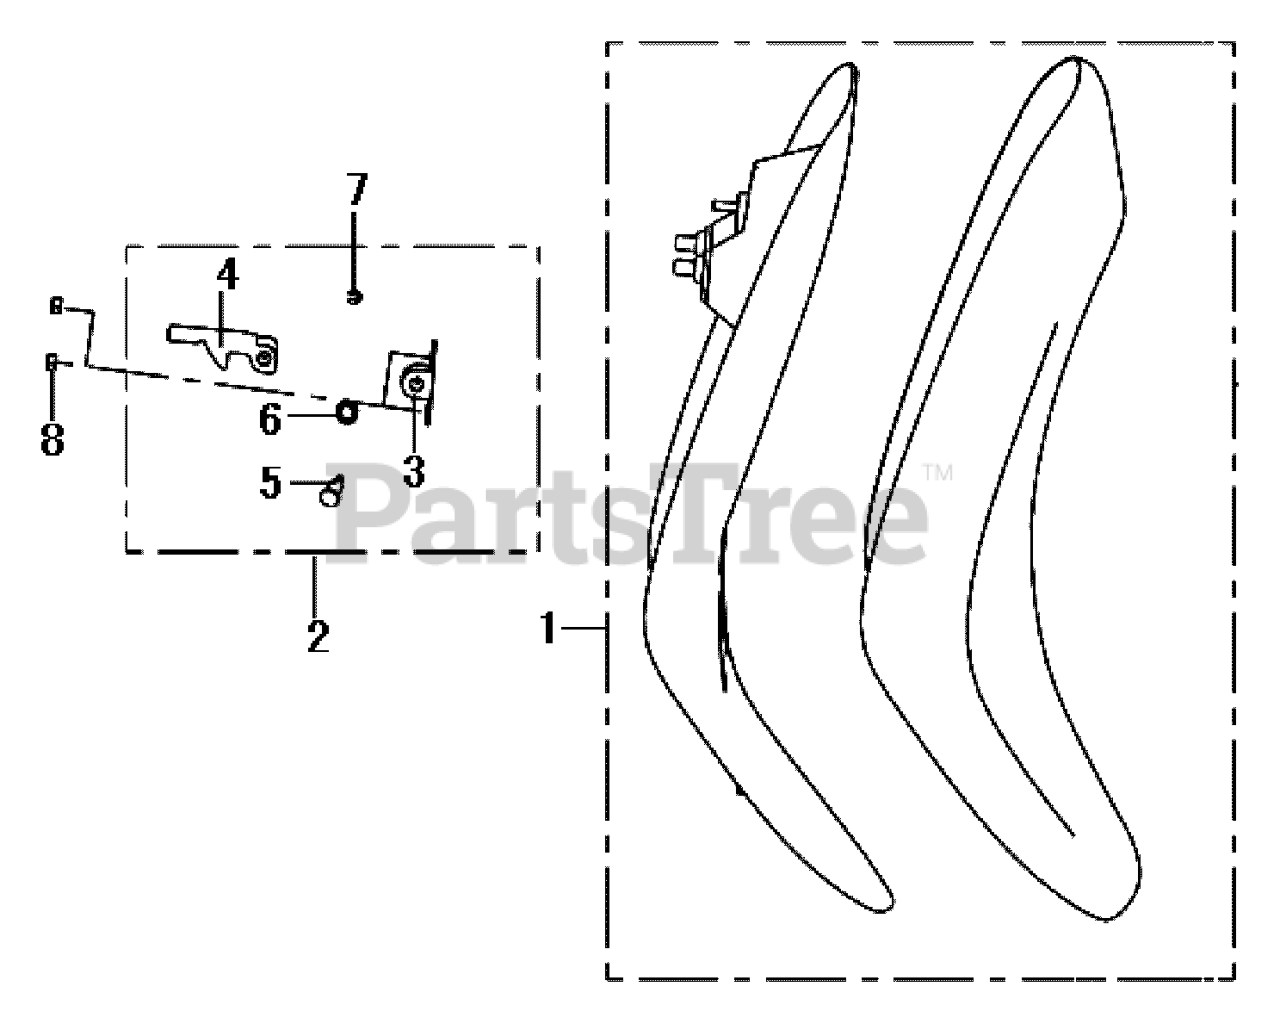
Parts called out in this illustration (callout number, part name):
1	SEAT ASSY.
2	SEAT LATCH ASSY.
3	LOCKING PLATE, SEAT
4	SEAT LATCH
7	CIRCLIP
